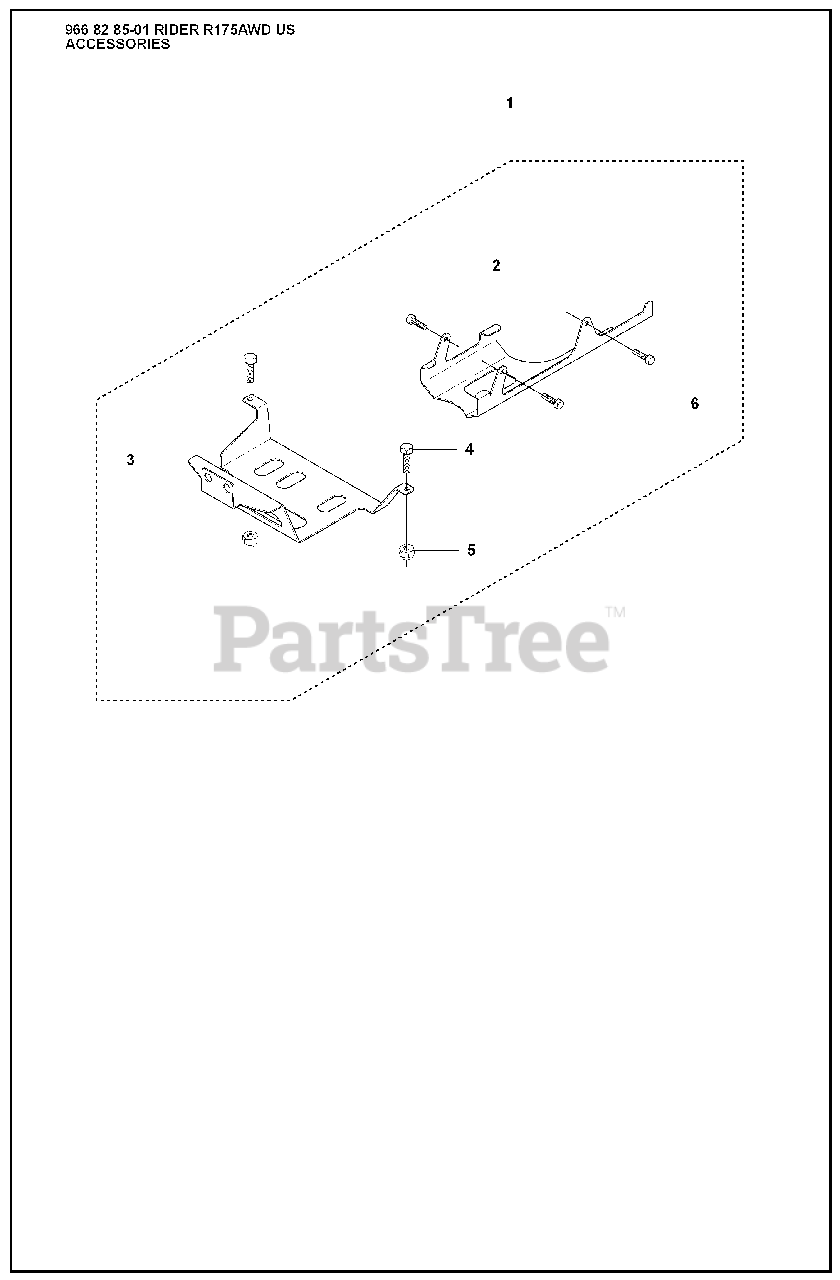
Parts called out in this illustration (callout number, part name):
1	AXLE PROTECTION KIT R
3	RP PROTECTION PLATE REAR
5	LOCKNUT M8
6	BOLT FLANGE - M8X16
